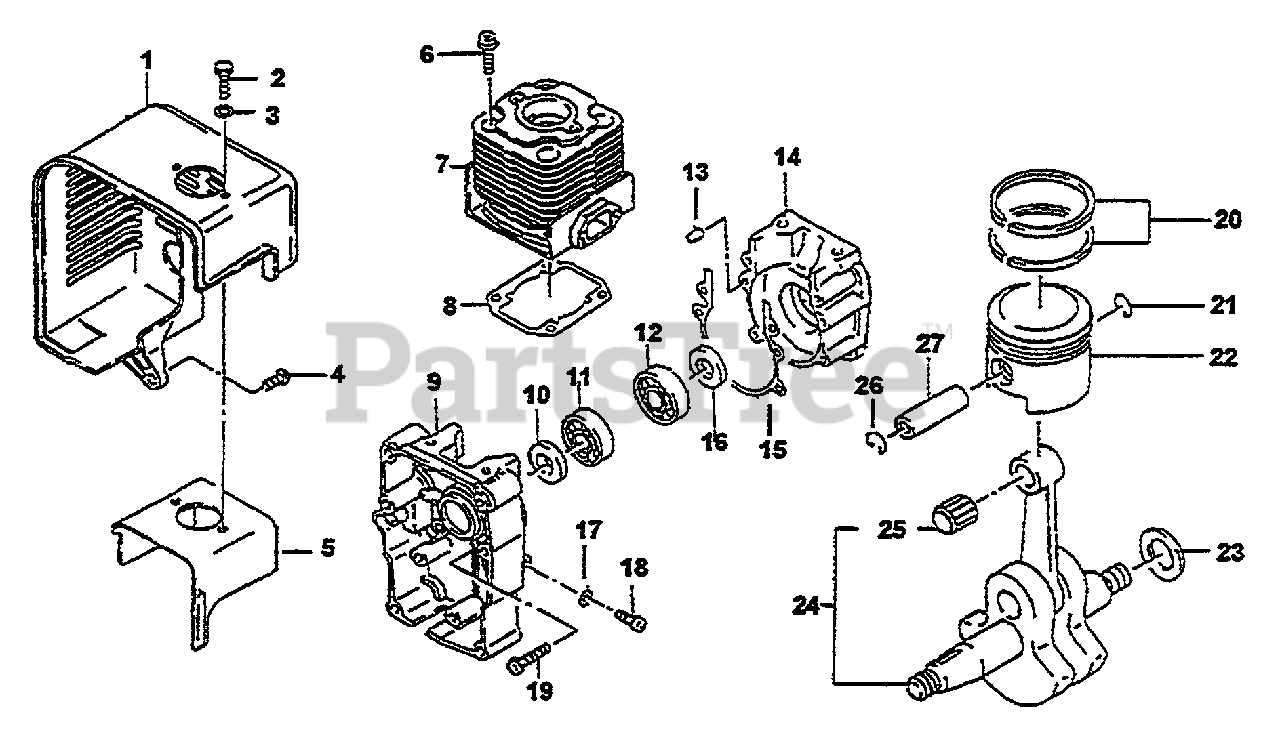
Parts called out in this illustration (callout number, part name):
1	SHROUD, ENGINE
5	SHROUD, ENGINE
8	GASKET, CYLINDER
9	CRANKCASE
10	SEAL
11	BEARING
12	BEARING
13	PIN, DOWEL
14	CRANKCASE
15	GASKET, CRANKCASE
16	SEAL
20	RlNG SET, PISTON
21	SNAP RING
22	PISTON
23	SHIM T=0.10
24	CRANKSHAFT ASSY
25	BEARING
26	SNAP RING
27	PIN, PISTON
